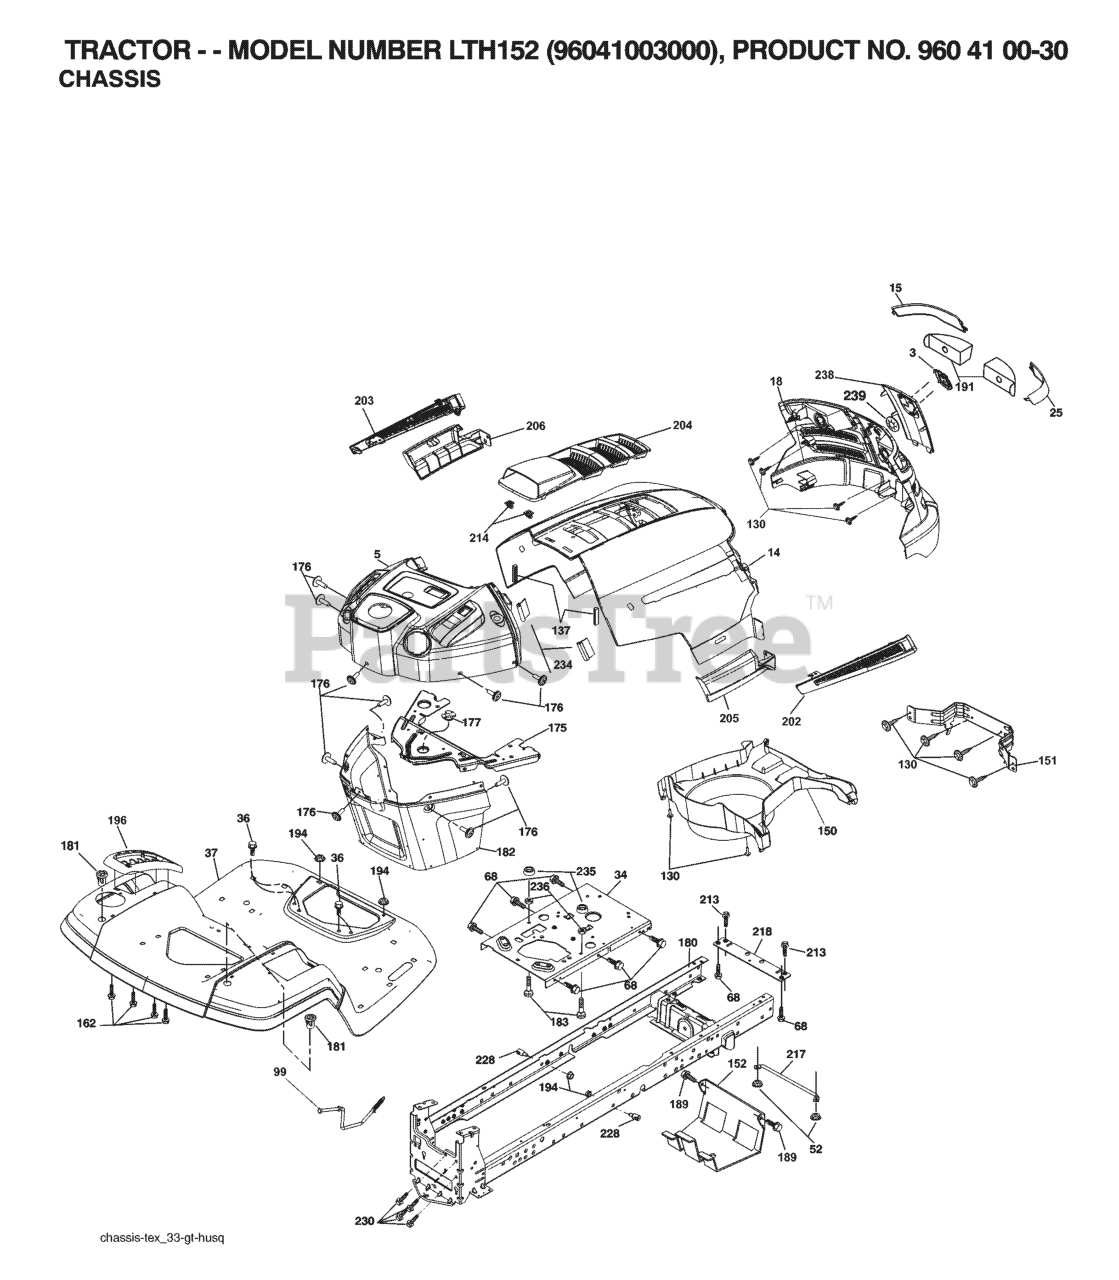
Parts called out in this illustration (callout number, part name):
3	RP LOGO
5	DASH
14	HOOD
15	LENS.HUSQVARNA LT.LH
18	RP GRILLE/LENS ASM.
25	LENS.HUSQVARNA LT.RH
34	PLATE.ENGINE.WELDED.CHASSIS
36	SCREW 5/16"
52	LOCKNUT
68	Screw 5/16-18 x 1/2 Hex, Self Tapping 5/16-18 x 1/2
99	ROD ASM BYPASS
130	SCREW
137	BUMPER DASH
151	BRACKET PIVOT
152	SHIELD.BROWNING.W/TEX
162	SCREW.HI-LO.CONSOLE
175	CROSSMEMBER
176	SCREW.#10-24X5/8.RN.QU
177	BUSHING STEERING
180	CHASSIS
181	BUSHING.MNT.FEND.CRGO.
182	DASH LOWER
183	BOLT.5/16-18X1-1/4 FULL.THREAD
189	SCREW
191	INSERT REFLECTIVE
194	NUT LOCK HEX FLANGE 5/16-18
196	CONSOLE.ASM.DECK.LIFT.
202	VENT SIDE HOOD RH
203	VENT SIDE HOOD LH
204	VENT TOP HOOD
205	SKIRT SIDE RH
206	SKIRT SIDE LH
213	BOLT
214	CLIP.RETAINER.TINNER.
217	ROD PIVOT CHASSIS/HOOD
218	X-PIECE.HOOD.STOP.NON/
228	STUD.FASTNER.W/ANTI-ROTATE
230	SHOULDER BOLT 5/16-18TT
234	BUMPER.HOOD.TEX.HUSQVARNA
235	SPACER FENDER
236	NUT.CENTERLOCK.5/16-
238	TRIM
